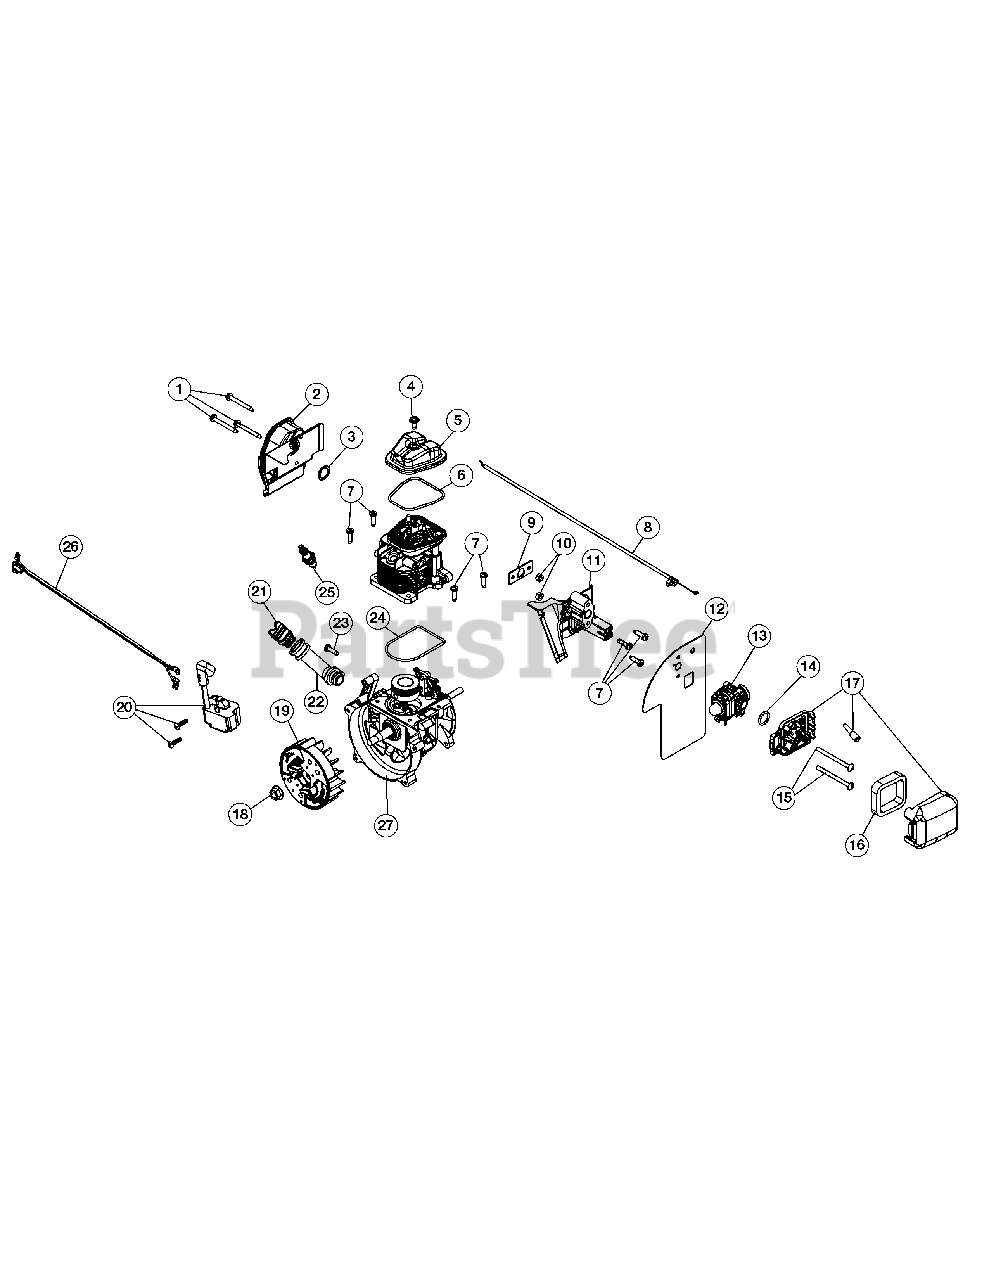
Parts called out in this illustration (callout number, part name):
1	Muffler Screws
2	Muffler Assembly (Incl. 1 & 3)
3	Muffler Gasket
5	Rocker Cover
7	Screw
8	Throttle Cable
9	Insulator Gasket
12	Carburetor Gasket
13	Carburetor
14	Carburetor O-Ring
15	Screw
17	Air Cleaner Assembly (Incl. 16)
19	Flywheel Asssembly
21	Oil Plug
22	Oil Fill Tube (Incl. 23)
25	Spark Plug
27	Short Block Assembly (Incl. 4-7 & 21-25)
